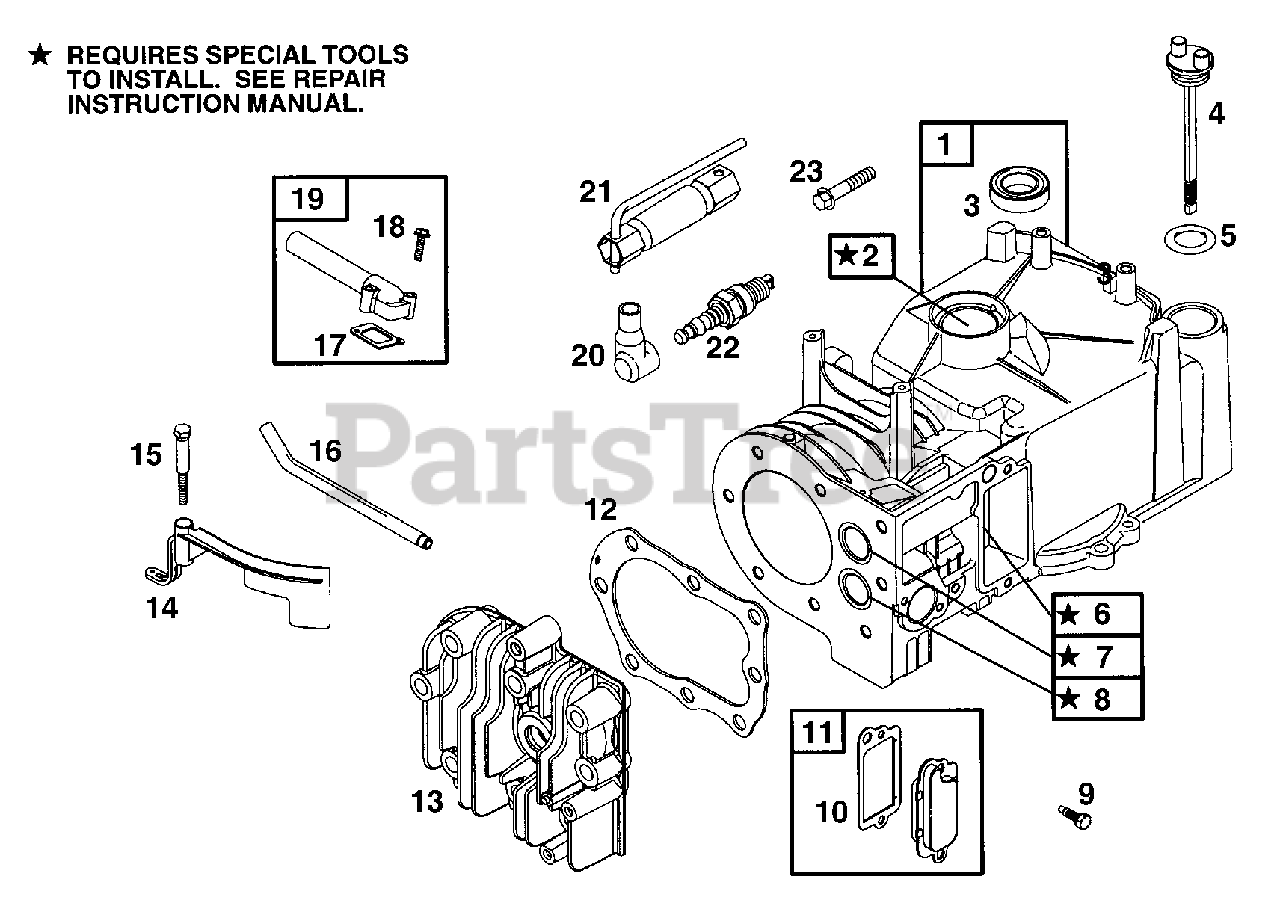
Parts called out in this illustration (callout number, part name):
1	Cylinder Assembly
2	Bushing
3	Oil Seal
4	Dipstick
5	O-Ring Seal
6	Guide Bushing (Exhaust)
7	Valve Seat (Intake)
8	Valve Seat (Exhaust)
9	Hex Screw
10	Breather Gasket
11	Breather Assembly
12	Cylinder Head Gasket
13	Cylinder Head
14	Governor Blade
15	Shoulder Screw
16	Breather Tube
17	Intake Gasket
18	Hex Screw
19	Intake Manifold
20	Spark Plug Boot
21	Spark Plug Wrench
22	Spark Plug
23	Hex Screw
